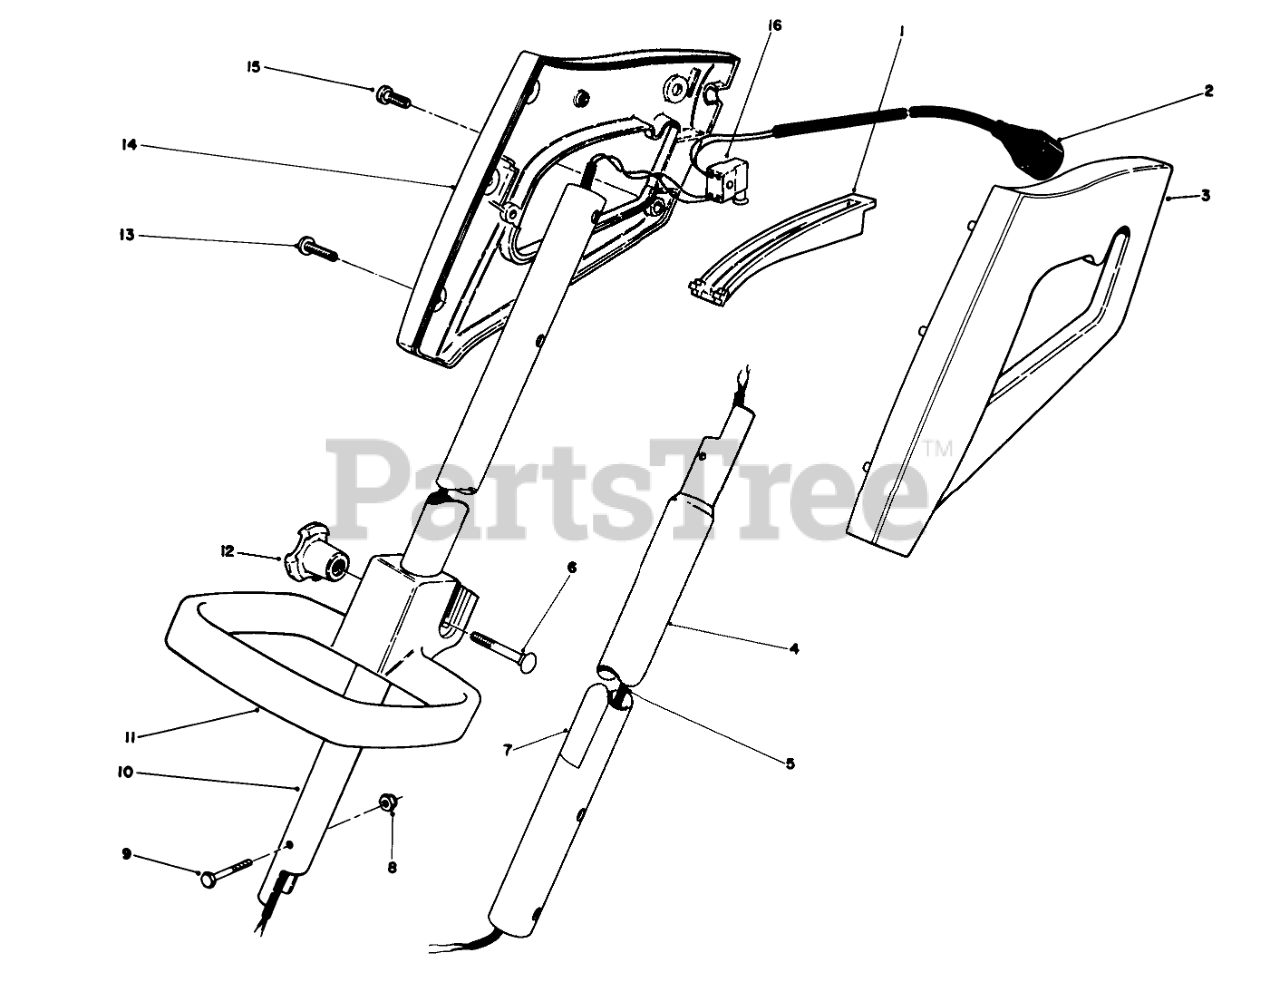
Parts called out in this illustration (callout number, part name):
1	Bar Switch
2	Cord-Power
3	Grip-L.H.
4	LOWER TUBING
5	WIRING HARNESS
6	BOLT-CARR
7	REP. SERIAL PLT
8	NUT-LOCK, NI
9	HEX HD MACHINE SCREW
10	UPPER EXT TUBING
11	Handle
12	Knob
13	Screw
14	Grip R.H.
15	SCREW-PPH
16	SWITCH
